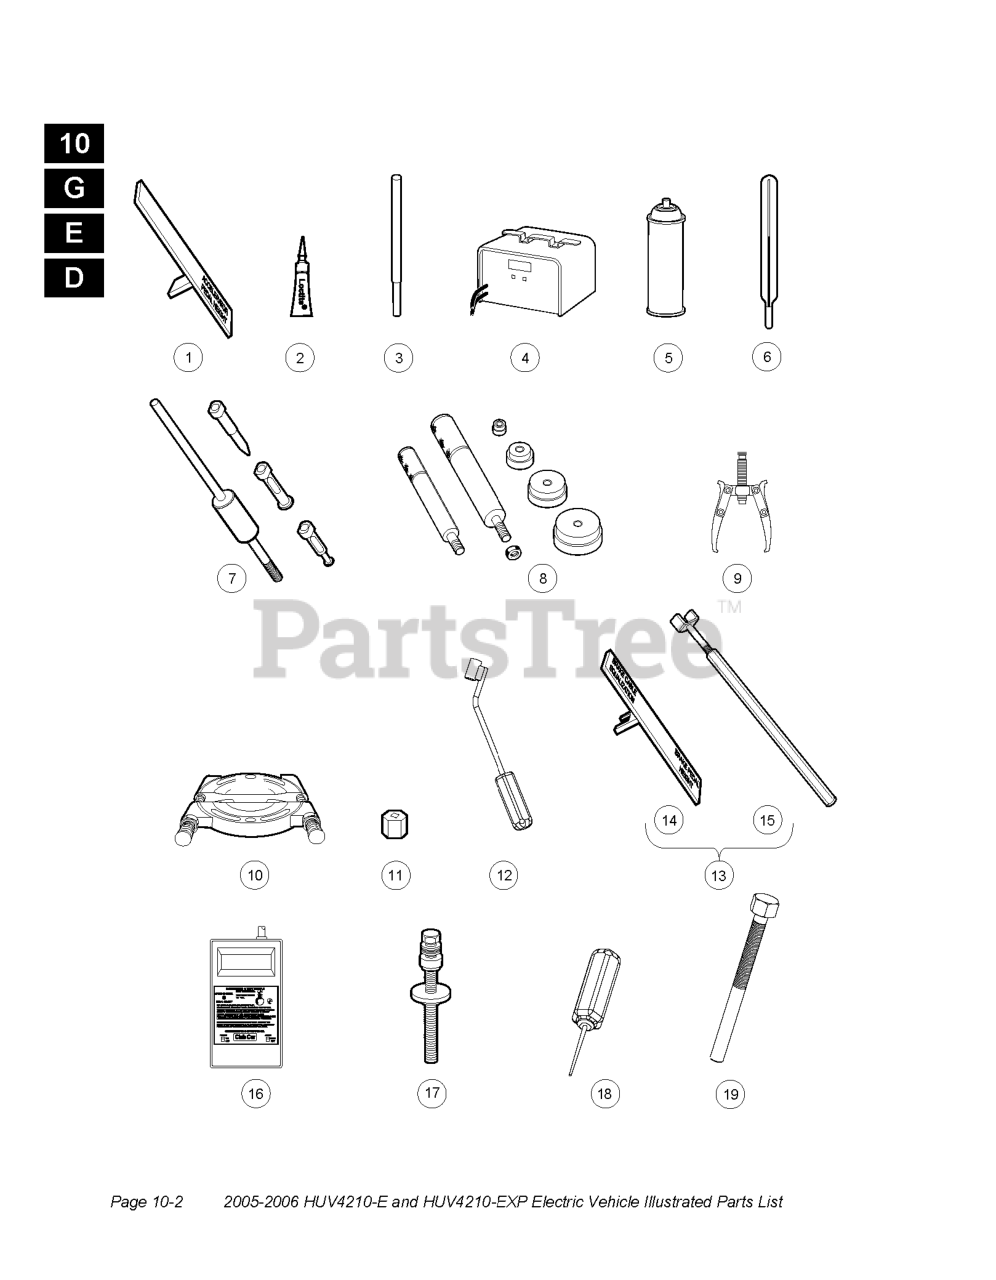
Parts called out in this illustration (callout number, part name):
1	TOOL, ACCEL. PEDAL ADJUSTMENT
2	GUIDE RING ADHESIVE 3 GRAMS
4	BATTERY DISCHARGE UNIT 36/48V
5	BATTERY TERMINAL PROTECT SPRAY
6	BATTERY THERMOMETER
7	BEAR & OIL SEAL REMOVER ASM
8	BEARING DRIVER SET
9	BEARING PULLER
10	BEARING PULLER WEDGE ATTACH.
11	BRAKE ADJUSMENT SOCKET TOOL
12	BRAKE CABLE RELEASE TOOL
13	BRAKE CABLE RELEASE TOOL
16	CALIBRATION & TEST MODULE
18	CHARGER BEZEL TOOL
19	TOOL, REMOVAL, CLUTCH, GAS/DSL
